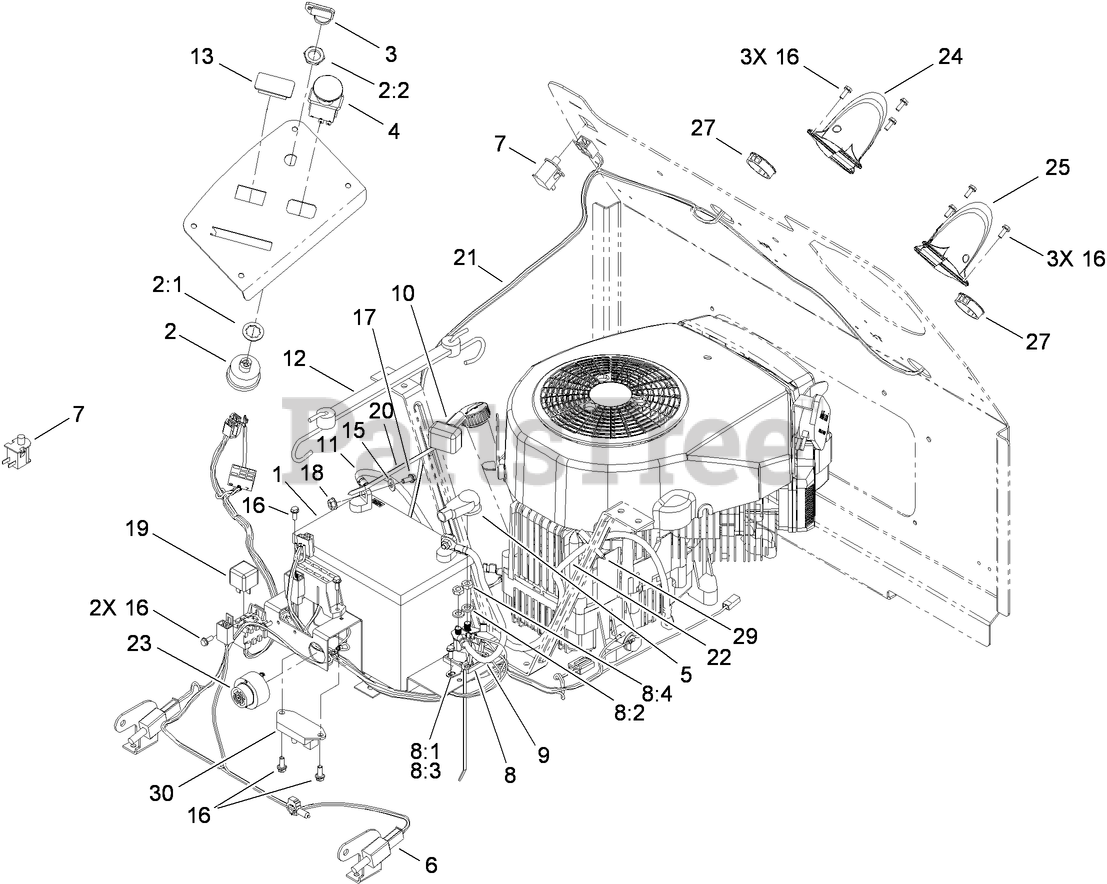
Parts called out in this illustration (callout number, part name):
2:1	WASHER-LOCK
2:2	NUT-HH
3	KEY-IGNITION
4	SWITCH-PTO,ON-ON-NONE
5	BOOT-TERMINAL
6	SWITCH
7	SWITCH-BAIL
8:1	WASHER-LOCK
8:2	WASHER-LOCK
8:3	NUT-HEX
8:4	NUT-JAM
9	CABLE-BATTERY, POSITIVE
10	BOOT-INSULATOR, TERMINAL
11	CABLE-NEGATIVE, BLACK
12	HOLDDOWN-BATTERY
13	PLUG-HOLE
15	WASHER-FLAT
16	SCREW-TAPTITE
17	SCREW-HH
18	NUT-HF
19	RELAY
20	TIE-CABLE
21	HARNESS-WIRE, KAWASAKI
22	WIRE-21 INCH
23	ALARM-TONE, DUAL
24	BAG SENSOR ASM
25	BAG SENSOR ASM
27	BUSHING-HARNESS, WIRE
29	CLAMP-HOSE
30	MODULE-DELAY
